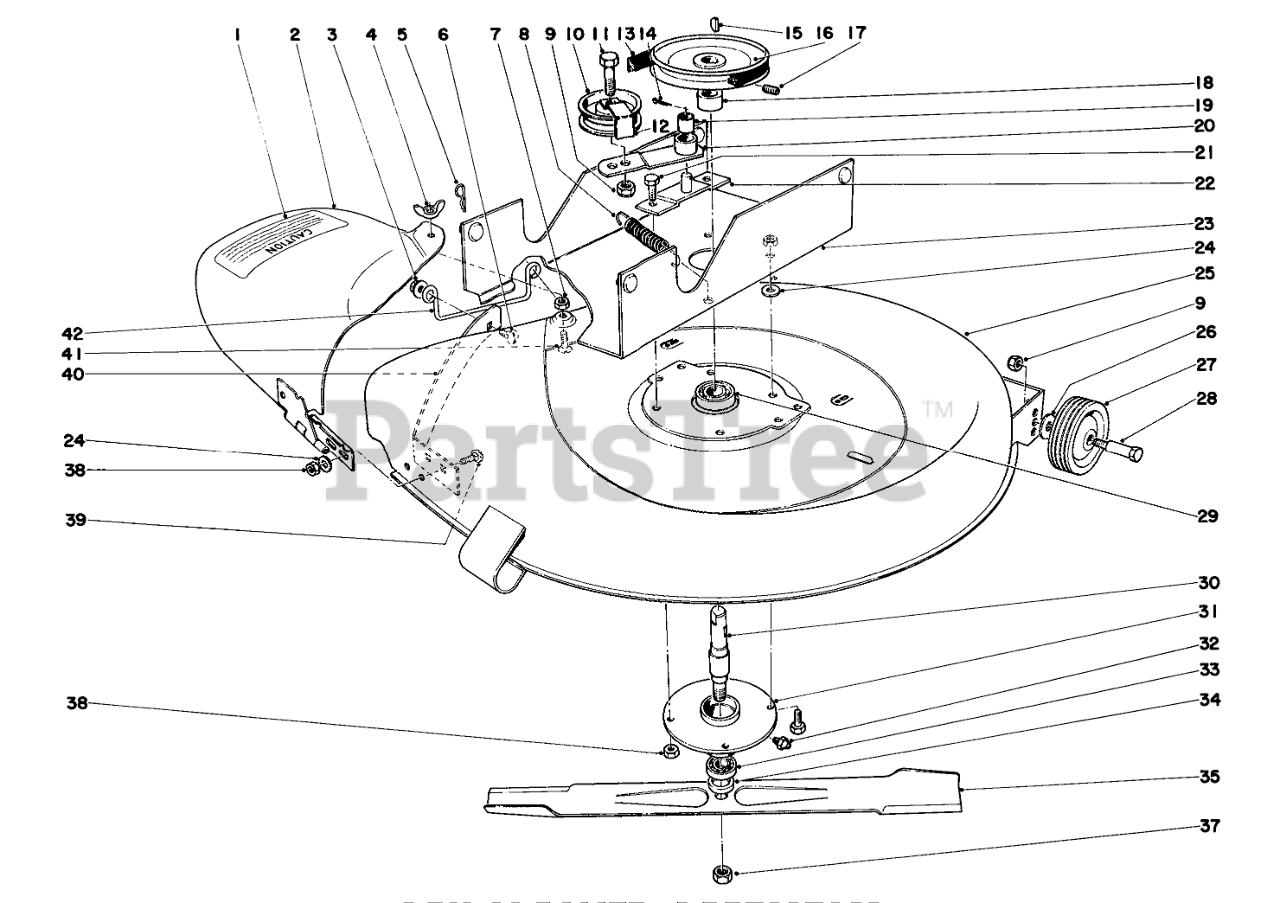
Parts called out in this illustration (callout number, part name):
1	Decal
2	Deflector
3	NUT-LOCK, HHF
4	Wing Nut
5	PIN-COTTER
6	SCREW-CARRIAGE
7	PAL NUT
8	Spring
9	NUT-LOCK, CONE
10	Idler Pulley
11	SCREW-HH
12	Belt Retainer
13	FRONT PULLEY BELT
14	PIN-COTTER
15	KEY-WOODRUFF
16	PULLEY
17	SCREW-HSH
18	Spacer
19	BUSHING
20	Idler Plate (Incl. Ref. #19)
21	SCREW-HH
22	Pivot Bracket
23	Channel
24	WASHER-PLAIN
25	Housing
26	WASHER-FLAT
27	Wheel
28	Axle Bolt
29	Bearing
30	Blade Spindle
31	MOWER SPINDLE HOUSING
32	FITTING-GREASE
33	.6693 RP BALL BEARING
34	Spacer
35	Blade
37	NUT-LOCK, CONE
38	NUT-LOCK, CONE
39	SCREW-CARR
40	Bar-Deflector
41	5/16-18X7/8 FLT HD MS
42	Bracket Foot Guard
